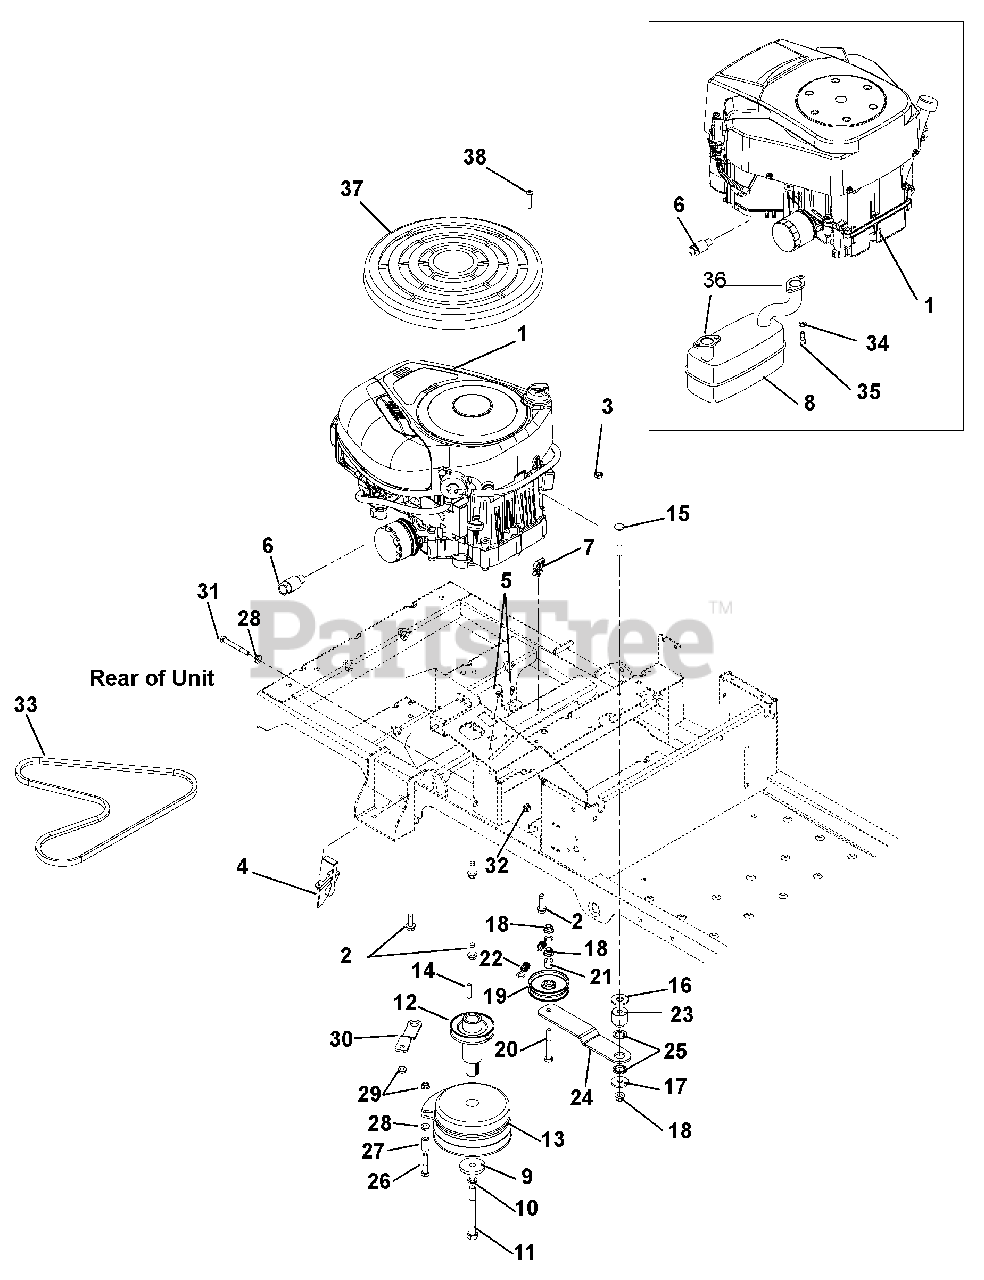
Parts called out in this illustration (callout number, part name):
1	ENGINE, B&S 14.5 POWERBUILT
1	ENGINE, KOHLER TWIN 20 HP
1	ENGINE, KOHLER TWIN - 22HP
2	@SCR-TAP .38-16X1.25 HWH TR YZ
3	@NUT-LK-CTR-JAM .375-16 YWZC
4	CABLE, THROTTLE
4	CABLE, CHOKE/THROTTLE COMBO
5	@SCR-TAP 10-24X.50 HWH TR YWZC
6	DRAIN, OIL
7	WIRE CLIP
8	MUFFLER, KOHLER TWIN
8	MUFFLER, B&S 500 BBZ
9	WSHR-FL-STL .469X2.00X.25 YWZC
10	@WSHR-LK .44X.109 REG YWZC
11	BLT-HEX .44-20X4.50 GR8 YWZC
12	WMT-PTO EXTENSION W/SHEAVE
13	CLUTCH, 105 FT*LB MONO POLE
14	KEY-SQ .25 X 1.25 X .25 SAE
15	@BLT-RDHDSQNK .38-16X2.75 G5YZ
16	@WSHR-FL-STL.563X1.38X.109YWZC
17	WSHR-FL-STL .406X1.375X.135 YZ
18	@NUT-LK-NYL-FLG .38-16 YWZC
19	PULLEY, ENGINE CLUTCH 03608
20	@BLT-HEX .38-16X2.75 GR5 YWZC
21	BSHG-SLV .391X.688X.52 PM
22	SPRING, EXTENSION
23	SPACER, GROUND DRIVE IDLER
24	IDLER ARM, GROUND DRIVE
25	BUSHING, IDLER ARM
26	SCR-CAP .31-18X1 3/4 S/HD YWZC
27	SPACER, RUBBER 5/16 IDX1.0 LG
28	@NUT-SPNLK-FLG .312-18 YWZC
29	@NUT-LK-TOP-FLG .31-18 YWZC
30	BRKT, CLUTCH STOP
31	@BLT-HEX .31-18X2.75 GR5 YWZC
32	@NUT-LK-NYL-FLG .31-18 YWZC
33	V-BELT, HA-RAW EDGE
34	@WSHR-LK .31X.078 REG YWZC
35	SCR-CAP .31-18X.75 S/HD
36	GASKET, MUFFLER COURAGE TWIN
37	GUARD, BRIGGS ENGINE (SINGLE)
38	SCREW, 8-16X.87 PHPAN 3 LOBE
